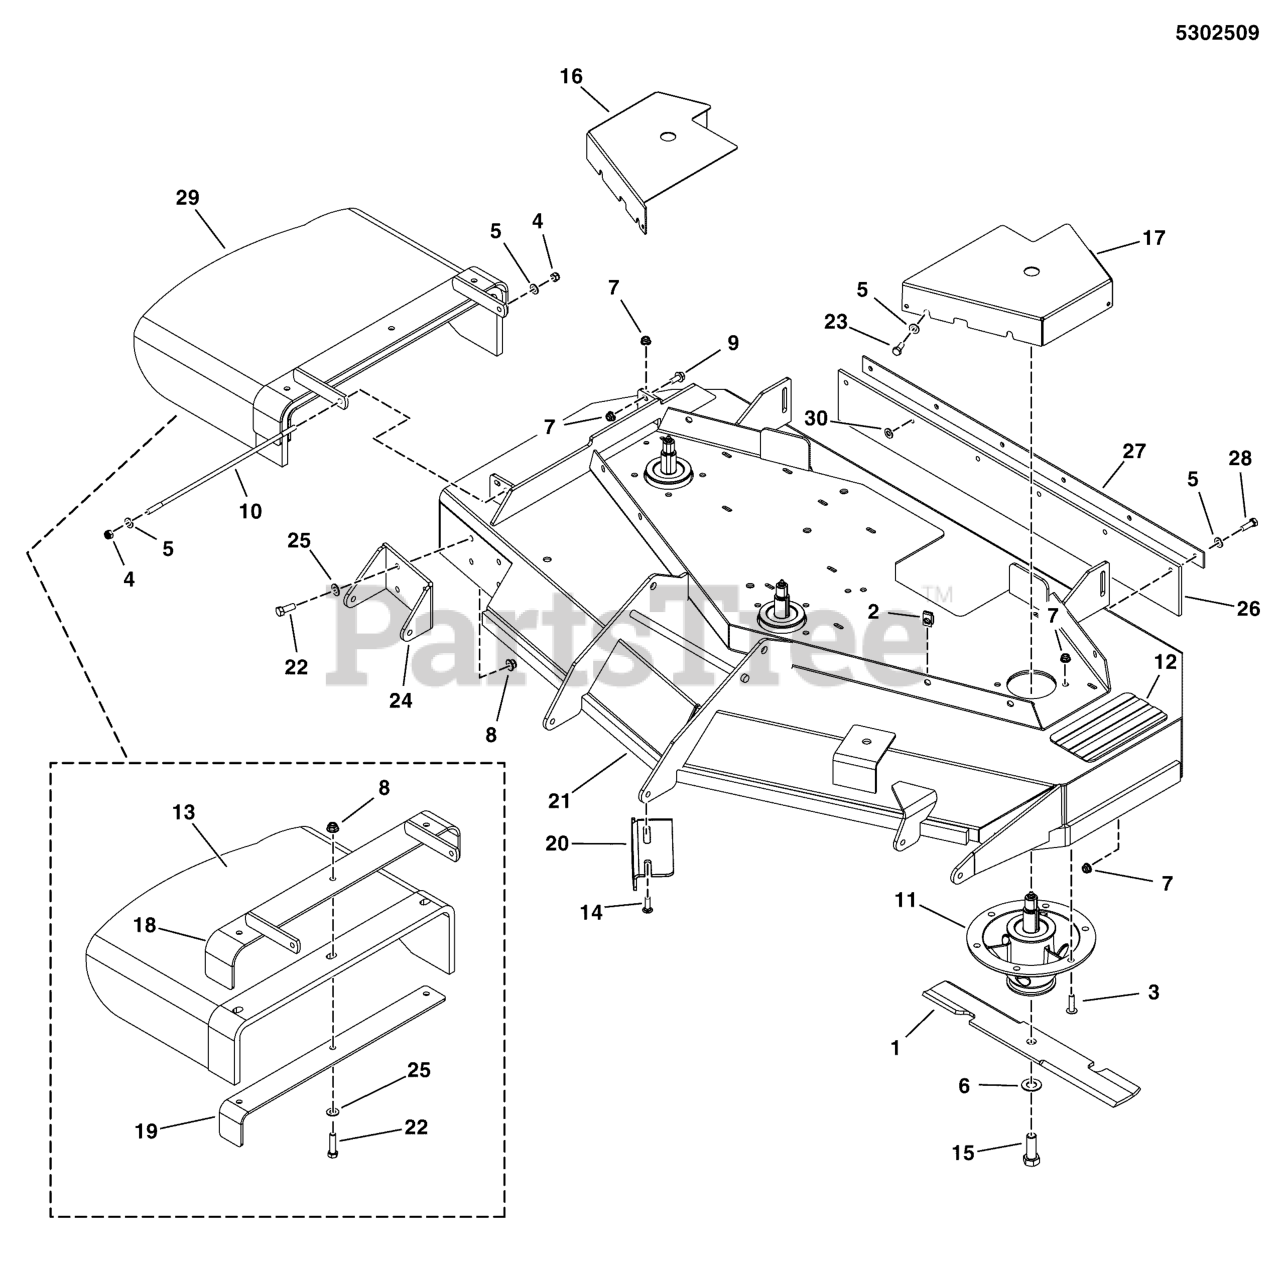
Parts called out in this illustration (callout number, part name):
1	BLADE, 18 X .25 X 2.5, 1 X 3.5 (SET OF 3)
2	BODY CLIP, 5/16-18-7GA MATERIAL
3	BOLT, 3/8-16 X 1, FLANGE, GD 5, CZ
4	NUT, 5/16-24 HEX NYLON LOCK
5	WASHER, 5/16" SAE
6	WASHER, 5/8 GRADE 8, YZ
7	NUT, 5/16-18 HEX NYLOCK FLANGE
8	NUT, 3/8-16 HEX NYLOCK FLANGE
9	BOLT, 5/16-18 X 3/4 GD5
10	ROD MOUNT, CHUTE 61"
11	SPINDLE ASSM, CAST IRON 8.0-6 BOLT
12	SAFETY WALK, 4.00 X 7.50
13	CHUTE, DISCHARGE, RUBBER, 61/72
14	BOLT, 5/16-18 X 3/4, CARRIAGE
15	BOLT, 5/8-11 X 1-3/4 GD8
16	GUARD, 52" DECK - RH - RED
17	GUARD, 52" DECK - LH - RED
18	WELD, FRAME, CHUTE, 61 - SNP RED
19	SUPPORT, DISCHARGE CHUTE - BLK
20	PLATE, DEFLECTOR - BLK
21	DECK SHELL W/DECALS, 52, S150XT
22	BOLT, 3/8-16 X 1-1/4" GD5 CZ
23	BOLT, 5/16-18 X 3/4 GD5
24	PLATE, BRACKET, ANTI SCALP - RED
25	WASHER, 3/8 SAE
26	FLAP, STRIPER, 52 DECK
27	PLATE, SUPPORT - BLK
28	BOLT, 5/16-18 X 1 GD5 YZ
29	KIT, DISCHARGE CHUTE
30	5/16 PUSH-ON NUT RETAINER, STL, CZ
